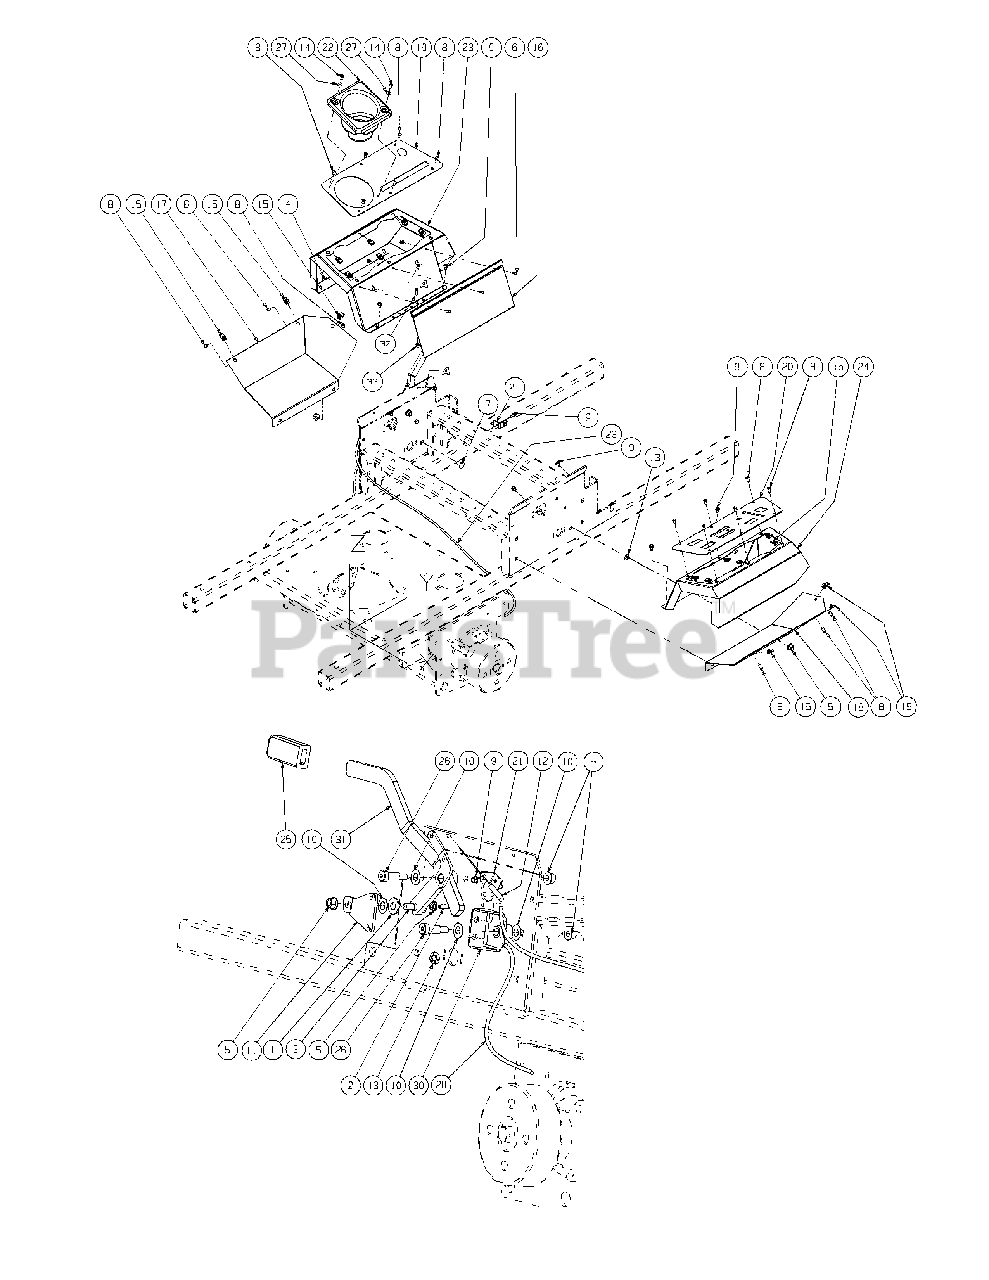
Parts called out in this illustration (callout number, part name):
1	Washer, 1/2 Zinc
2	Carriage Bolt, 3/8-16, 1.00
3	Shoulder Bolt, 1/2 x 1/2
4	Lock Nut, Nylon Insert, 10-32
5	Flange Lock Hex Nut, 3/8-16
6	Phillips Head Machine Screw, 10-32 x 5/8
7	Carriage Bolt, 3/8-16 x .75
8	Screw Button Head, 1/4-20 x .5
9	Screw, TT, 1/4-20, 0.5, Hex Index Washer
10	Washer, .508 ID x 1.0 OD x .020
11	Centering Bracket
12	Left Hand Brake Cable
13	Push Retainer, 3/8
14	Screw, #10-32 x 0.500
15	U-Nut, 1/4-20
16	Bag, Debris Storage
17	Lower Panel, LH
18	Lower Panel, RH
19	Control Panel Cover, LH
20	Control Panel Cover, RH
21	Brake Cable Mounting Bracket
22	Cup Holder
23	Control Panel, LH
24	Control Panel, RH
25	Parking Brake Grip
26	Shoulder Bolt, 1/2 x 1.00, 3/8-16
27	Washer, 3/16
28	Brake Cable, LH
29	Brake Cable, RH
30	Brake Cable Bracket
32	Screw, Hex, Cap, 1/4-20 x .75
33	Lock Nut, 1/4-20
